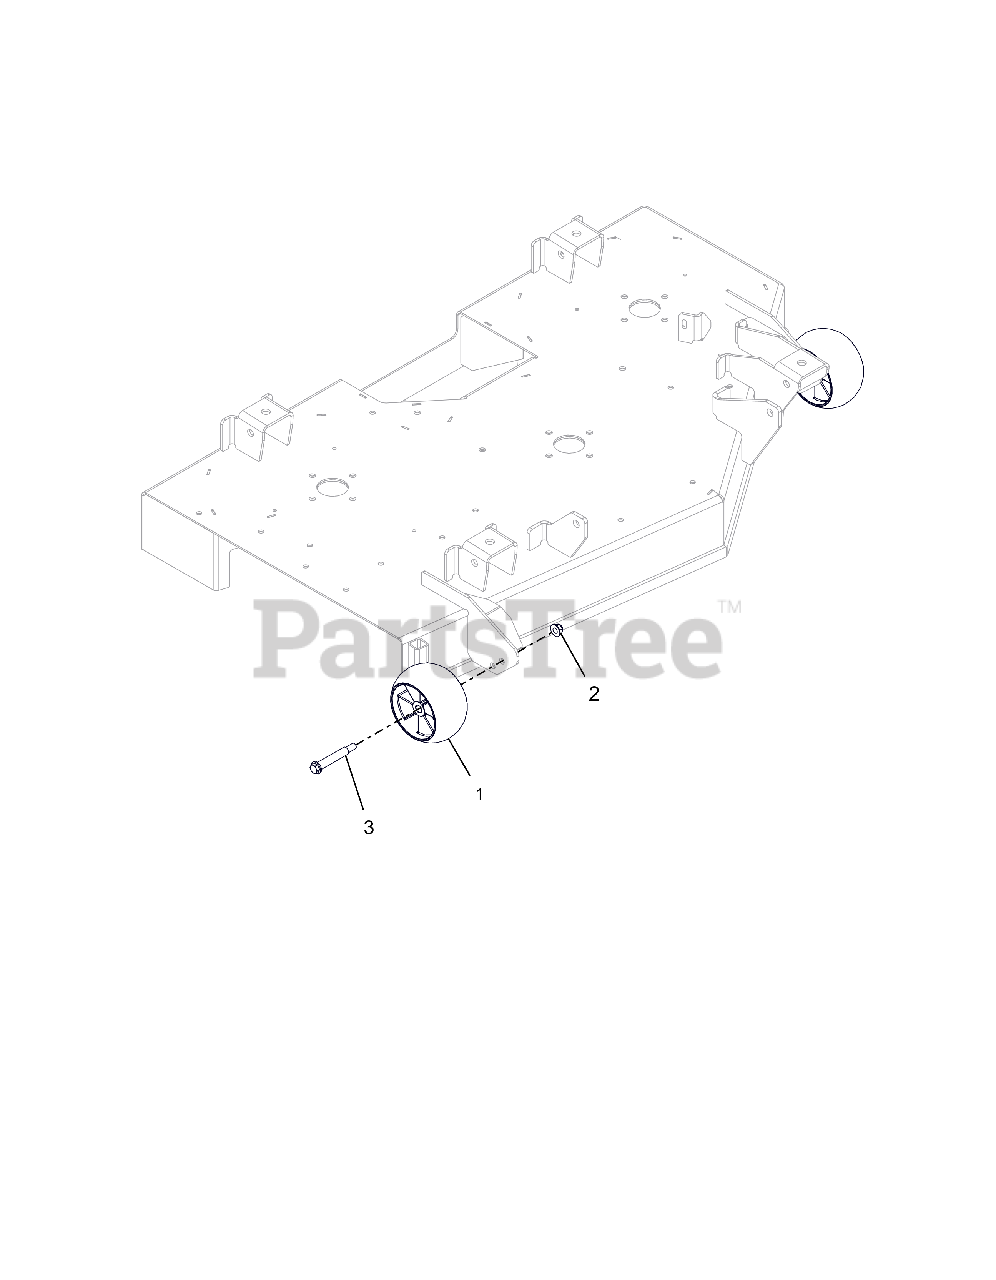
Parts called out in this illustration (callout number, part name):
1	ANTI-SCALP WHEEL - 5X OS
2	NUT,NYL-FLG .38-16 GF ZCC
3	BLT-SHLDR .38-16X2.50 HWH G5
